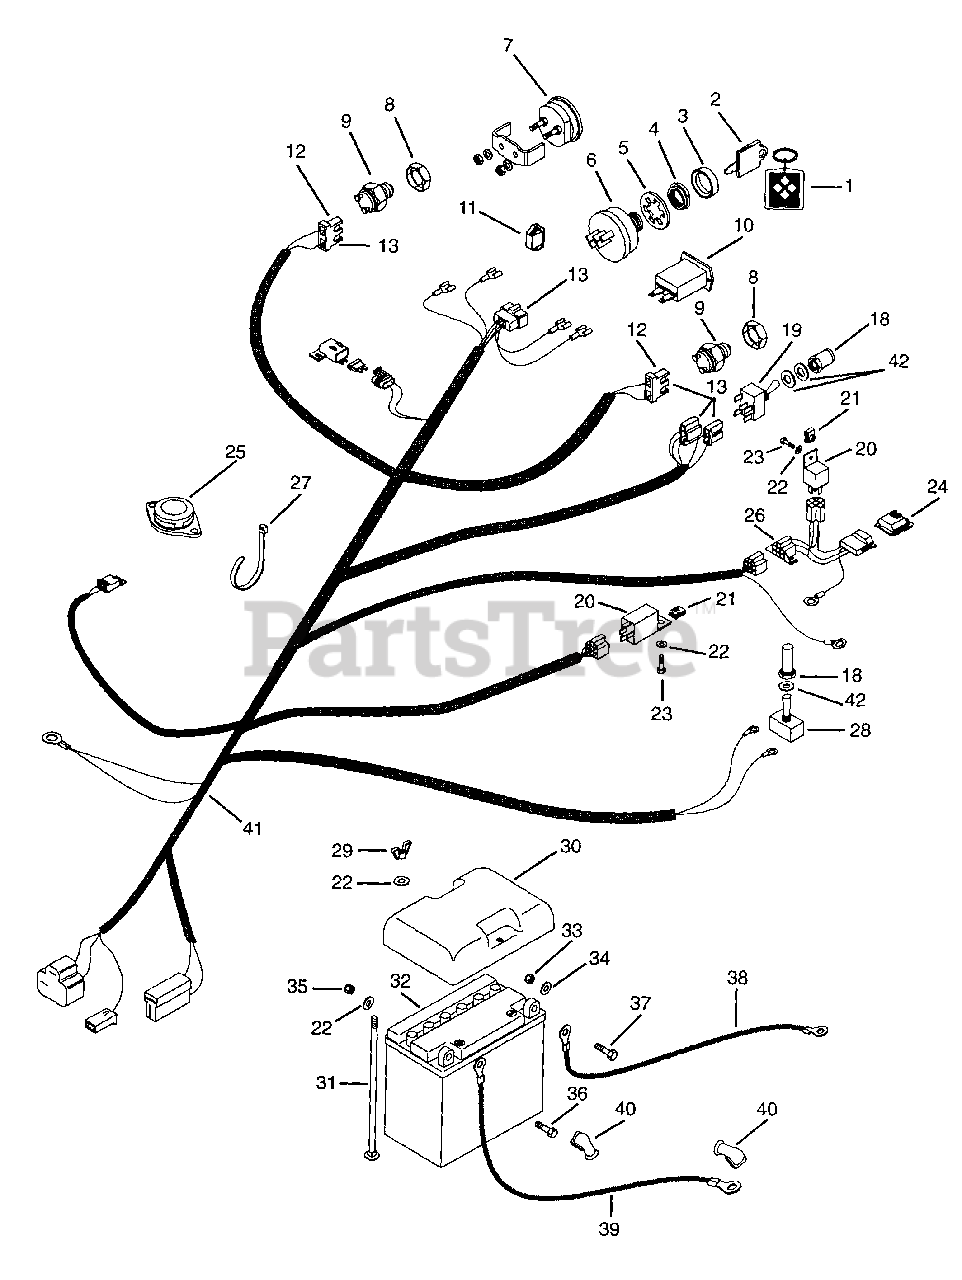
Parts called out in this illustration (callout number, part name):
1	Key Chain
2	Ignition Switch Key
3	Cap-Ignition Switch
4	Nut-Panel .562-24
5	Washer-Lock Internal .625 x .045
6	Ignition Switch
7	Gauge-Ammeter
8	Nut-Stamped .56-18
9	Switch-Neutral Start N.O.
10	Hour Meter
11	Light-Indicator
12	Connector-2-Wire Switch 2
13	Terminal
14	Cover
15	Fuse-25 AMP
16	Assembly-Connector Weather Tight
17	Terminal-For 10-12 Ga Wire
19	Switch Assembly
20	Relay
21	Nut-Speed .25-20
22	Washer-Flat-Steel .281 x .620 x .065
23	Bolt-Hex .25-20 x .75 Grade 5
24	Module-Time Delay
25	Switch-Seat 4
26	Adapter Harness
27	Tie Wrap-Black
28	Switch Assembly
29	Nut-Locking-Wing .250-20
30	Cover-Battery
31	Bolt-Round Head Square Neck Grade 25-20 x 7.00 Grade 2
32	12 Volt Battery (8 HP)
33	Nut-Locking-Center .31-18
34	Washer-Flat-Steel .344 x .688 x .065
35	Nut-Locking-Center .25-20
36	Bolt-Hex .25-20 x .75 Grade 5
37	Bolt-Hex .31-18 x 1.00 Grade 5
38	Cable-Negative Battery
39	Cable-Battery To Solenoid
39	Cable-Positive Battery
40	Boot Insulator
41	Harness-Wiring
42	Washer-Flat-Steel .344 x .688 x .065
